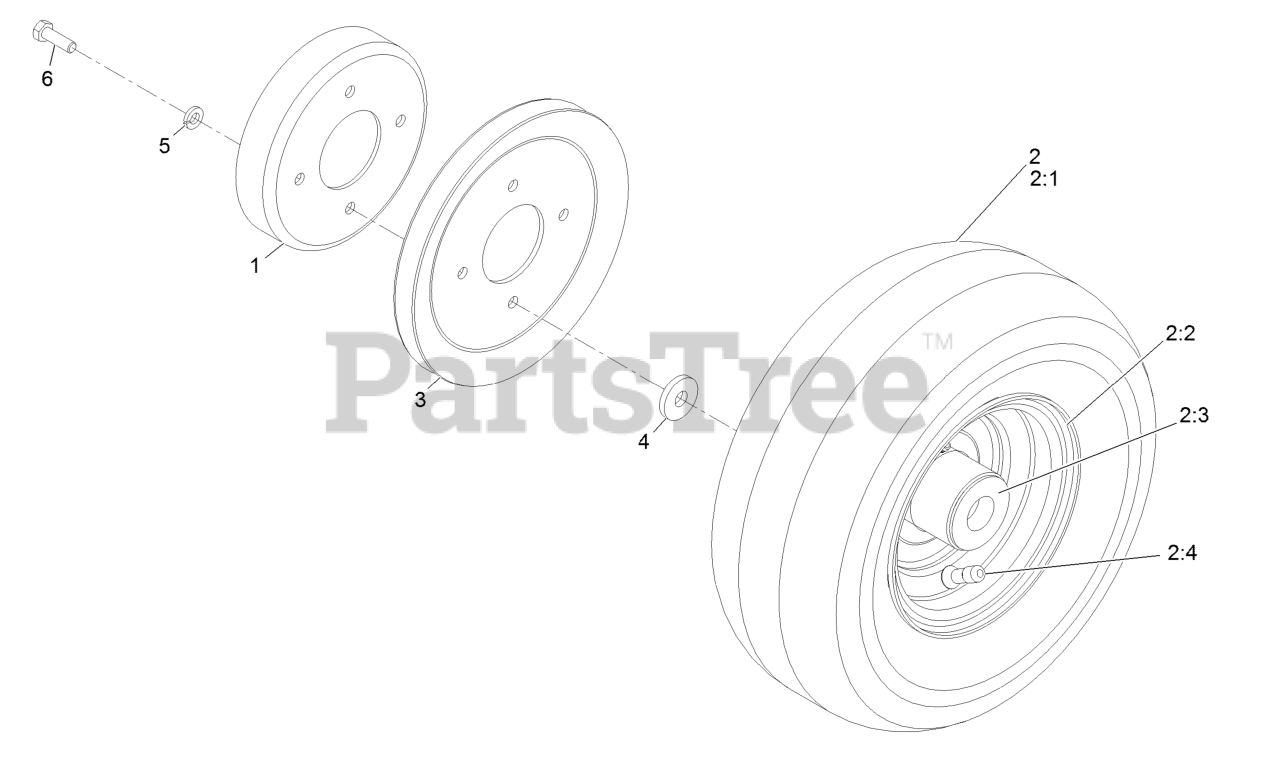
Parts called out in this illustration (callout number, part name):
1	Drum-Brake
2	Wheel And Tire ASM
2:2	Wheel And Hub ASM
2:3	Stem-Valve
2:4	Zerk 1/4-28 Str Thrd Forming
3	Sheave-Wheel, Drive
5	Washer-Lock 5/16 Heavy
6	Screw-HH 5/16-18 X 1
